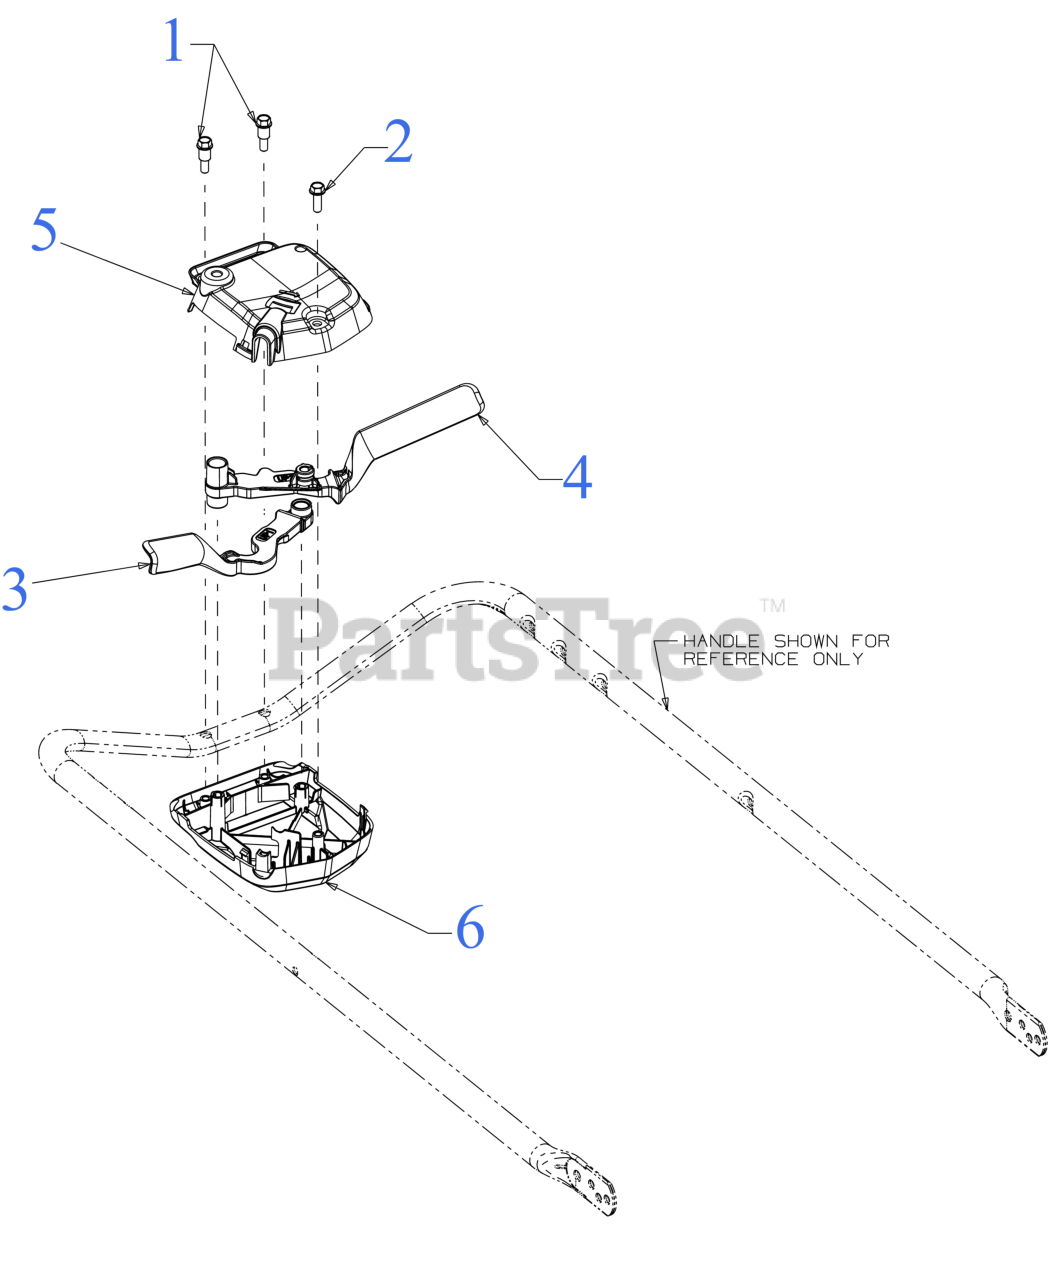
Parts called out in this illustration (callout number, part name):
1	SHOULDER SCREW 1/4-15 x .970
2	SCREW 1/4-15 x .750
3	CONTROL LEVER (LH)
4	CONTROL LEVER (RH)
5	CONTROL HOUSING (LOWER)
6	CONTROL HOUSING (UPPER)
